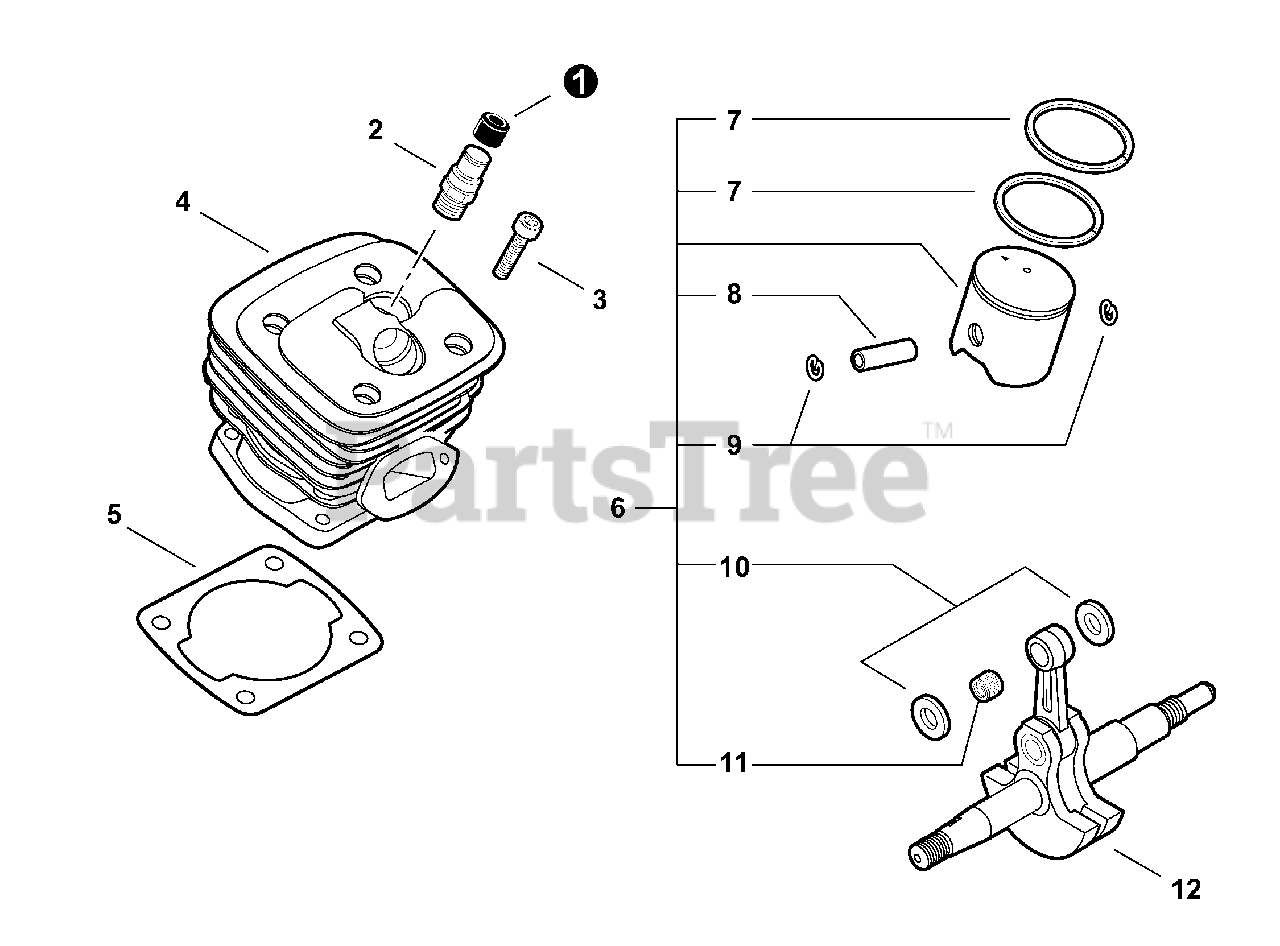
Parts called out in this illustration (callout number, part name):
1	COVER, DUST
2	VALVE ASSY, DECOMPRESSION
3	BOLT, TORX 5×25
4	CYLINDER
5	GASKET, CYLINDER
6	PISTON KIT
7	RING, PISTON
8	PIN, PISTON
9	RING, SNAP Ø11
10	WASHER, THRUST
11	BEARING, NEEDLE 11
12	CRANKSHAFT ASSY
